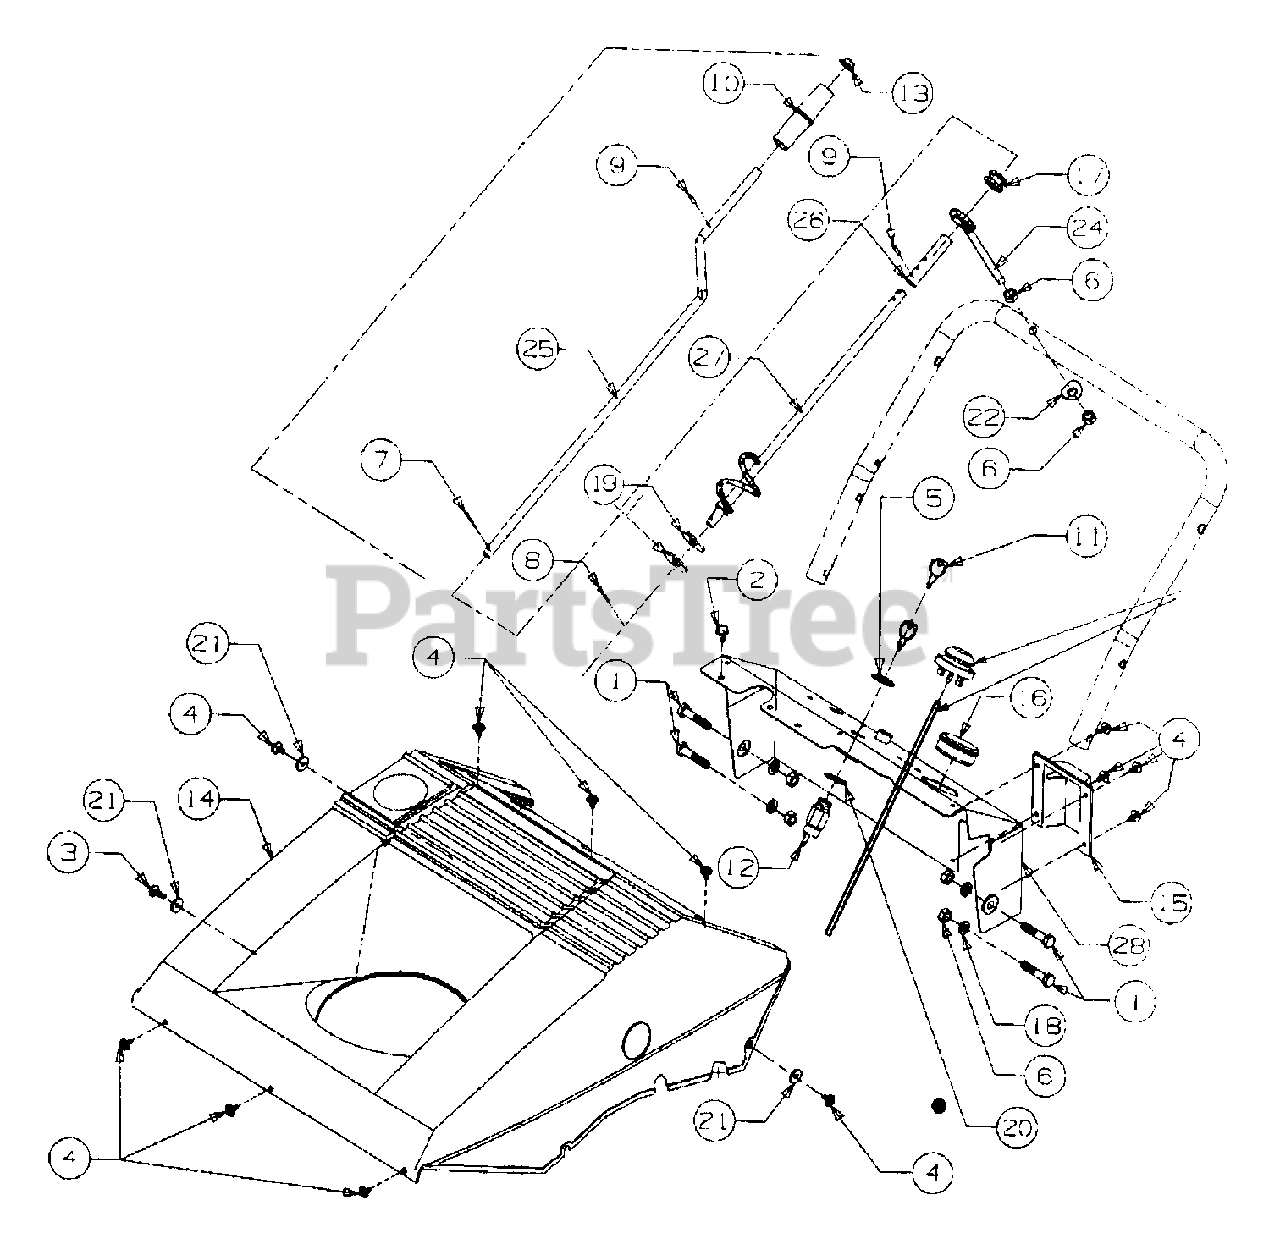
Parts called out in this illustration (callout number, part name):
1	Screw-Hex
2	Screw-Hex Washer
3	Screw-Hex
4	Screw-Hex
5	Nut-Jam
6	Nut-Hex
7	Hairpin
8	Pin-Cotter
9	Pin Roll
11	Key-Ignition
12	Switch
13	Cap-Push
14	Shroud-Black
15	Cover-Choke
16	Plug-Insert
17	Grommet-Rubber
18	Washer-Lock
19	Washer-Flat
20	Washer-Lock-Internal
21	Washer-Flat
22	Washer-Saddle
24	Eyebolt-Chute Crank
26	Spacer
